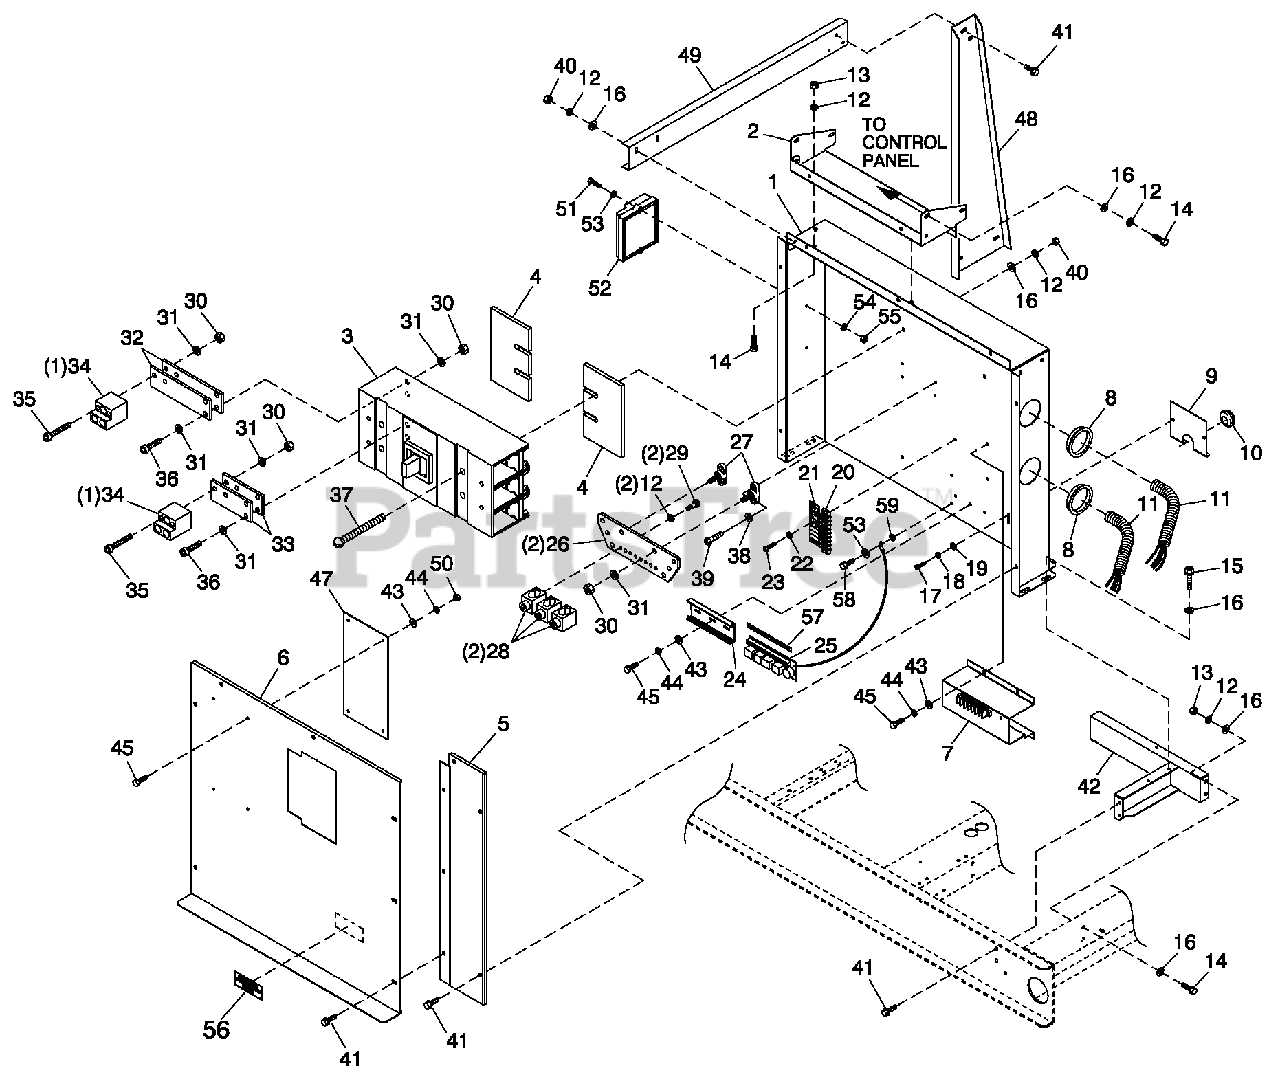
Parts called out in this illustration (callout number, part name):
1	PANEL CB CONNECTION
2	MOUNT CONTROL PANEL CPL
3	CB 0700A3P 600VSLMD6 LL
4	INSULATOR (NOMEX)
5	COVER FIXED LMD CB
6	COVER SERVICE LMD CB
7	ASSY PCB INTERFACE 1PH 240V
8	BUSHING SNAP SB-2.5-31
9	PLATE WIRE SNGL GALV
10	GROMMET 1.25X.25X.75
11	CONDUIT FLEX 2.0" ID (36" LG)
12	WASHER LOCK M6-1/4
13	NUT HEXM6X1.0G8YEL CHR
14	SCREW HHC M6-1.0X 16 G8.8
15	SCREW HHTT M6-1.0X16ZYC
16	WASHER FLAT 1/4-M6 ZINC
17	SCREW PHTT M5-0.8 X 16 ZYC
18	WASHER LOCK M5
19	WASHER FLAT M5
20	BLOCK TERM 20A 8 X 6 X1100V
21	DECAL CPL CUST CONN H CTRL
22	WASHER LOCK #6
23	SCREW PHTT #6-32 X 1/2 ZYC
24	RAIL SNAPTRACK PCB HOLDER BULK
25	ASSY RELAY PCB 12VDC
26	BUBAR NEUTRAL BLOCK (520/MAR)
27	JUNCTION BLOCK 3/8-16
28	LUG SLDLSS 600/250-1/0 X 1/4-28
29	SCREW HHC 1/4-28 X 5 /8 .625TH
30	NUT HEX 3/8-16 STEEL
31	WASHER LOCK 3/8
32	BUSBAR 1/4X2 LMD L1
33	BUSBAR 1/4X2 LMD L2
34	LUG SIEMENS LMD/LDTA3K500
35	SCREW SHC 3/8-16 X 3.0 BLK OX
36	SCREW SHC 3/8-16 X 1.25 G8.8 Z
37	SCREW RHM 1/4-20X3-1/2
38	WASHER LOCK M5
39	SCREW PHTT M5-0.8 X 16 ZYC
40	NUT HEX 1/4-20 STEEL
41	SCREW THF M6-1 X 16 N WA Z/JS
42	CHAN ASSY CB SUPPORT
43	WASHER FLAT M4
44	WASHER LOCK #8-M4
45	SCREW PHTT M4-0.7 X 10 ZYC
47	INSUL CB COVER
48	CHANNEL SUPPORT
49	CHANNEL BRACE
50	NUT HEX M4-0.7 G8YEL CHR
51	SCREW PPHM #10/32X2
52	CTRL IGN MODULE
53	WASHER FLAT #10 ZINC
54	WASHER LOCK #10
55	NUT HEX #10-32 STEEL
56	DECAL CUSTOMER CONNECT INSIDE
57	DECAL H-100 RB3 CUST CONN
58	SCREW HHTT M4-0.7X8ZP
59	WASHER SHAKEPROOF EXT #10 STL
